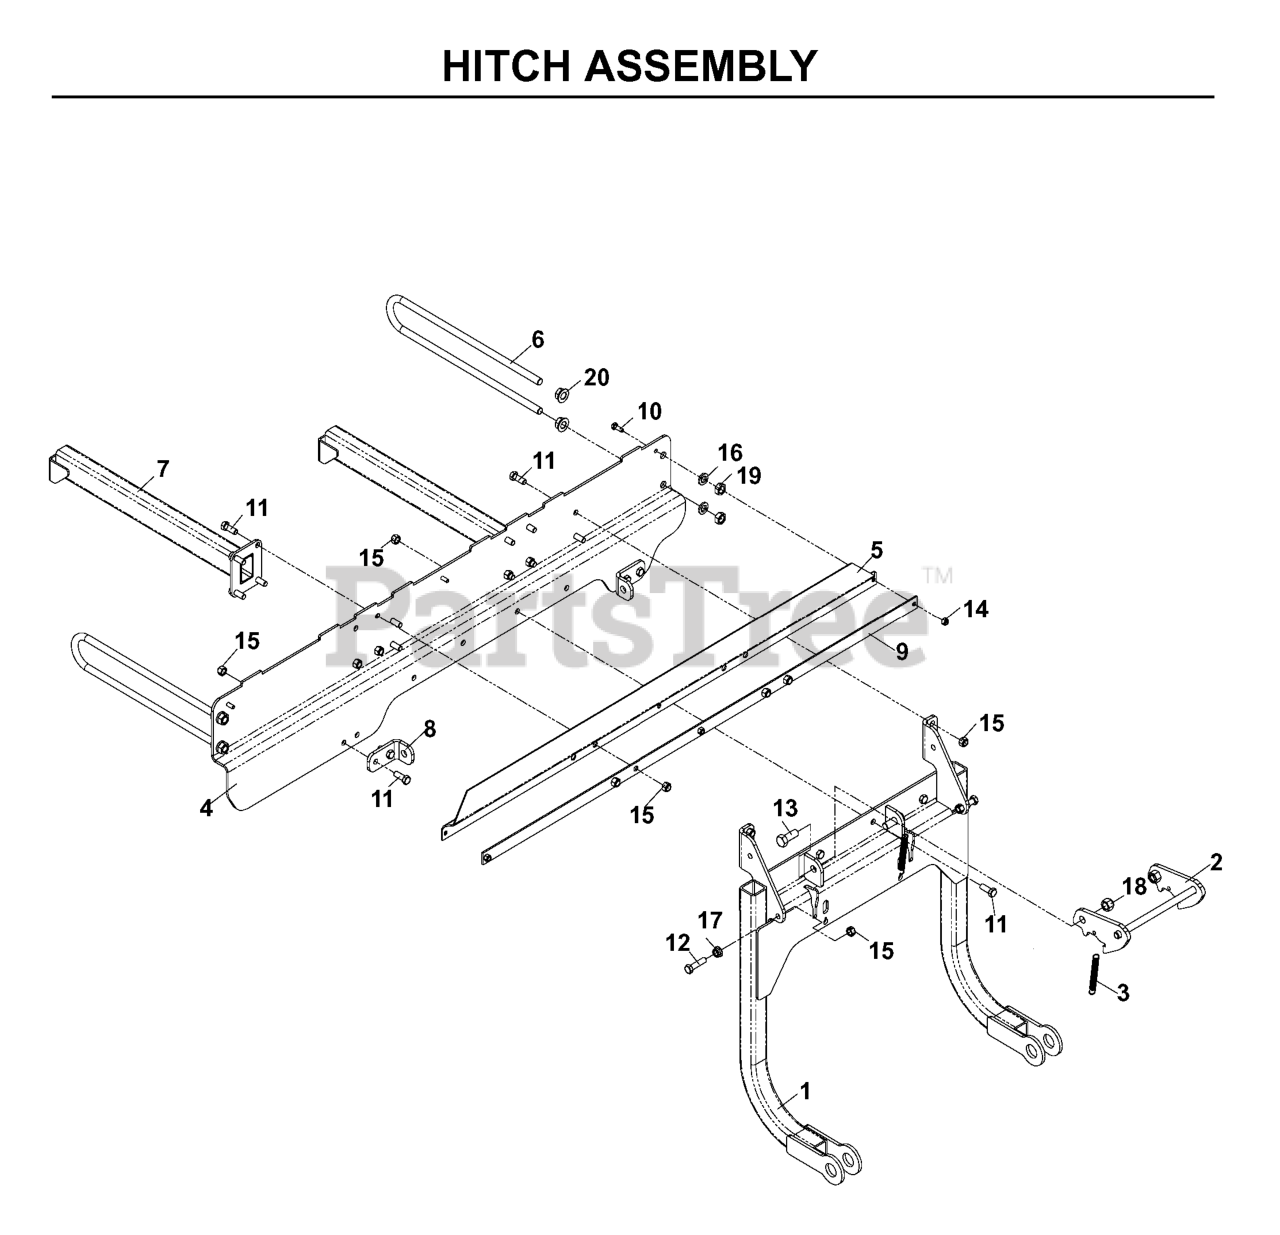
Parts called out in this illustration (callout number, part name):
1	HITCH WELDMENT
2	LATCH WELDMENT
4	MOUNT Z BRACE
5	SEAL, RUBBER
6	SUPPORT, OUTER
7	SUPPORT ARM WELDMENT
8	BRACKET, SUPPORT
9	SEAL STRAP
10	HCS 1/4C X 3/4 HCS
11	HCS 3/8-16X1.GRD.5.ZD
12	HCS 3/8C X 1 1/2
13	HCS 1/2-13 X 1-1/4
14	NUT.1/4-20.HEX.NYLOC.ZD
15	NUT 3/8-16 NYLOC
16	WASHER 1/2" SPLIT LOCK
17	NUT 3/8C WHIZ
18	NUT 1/2-13 HEX NYLOC ZD
19	NUT 1/2 HEX JAM
20	NUT 1/2-13 HEX
